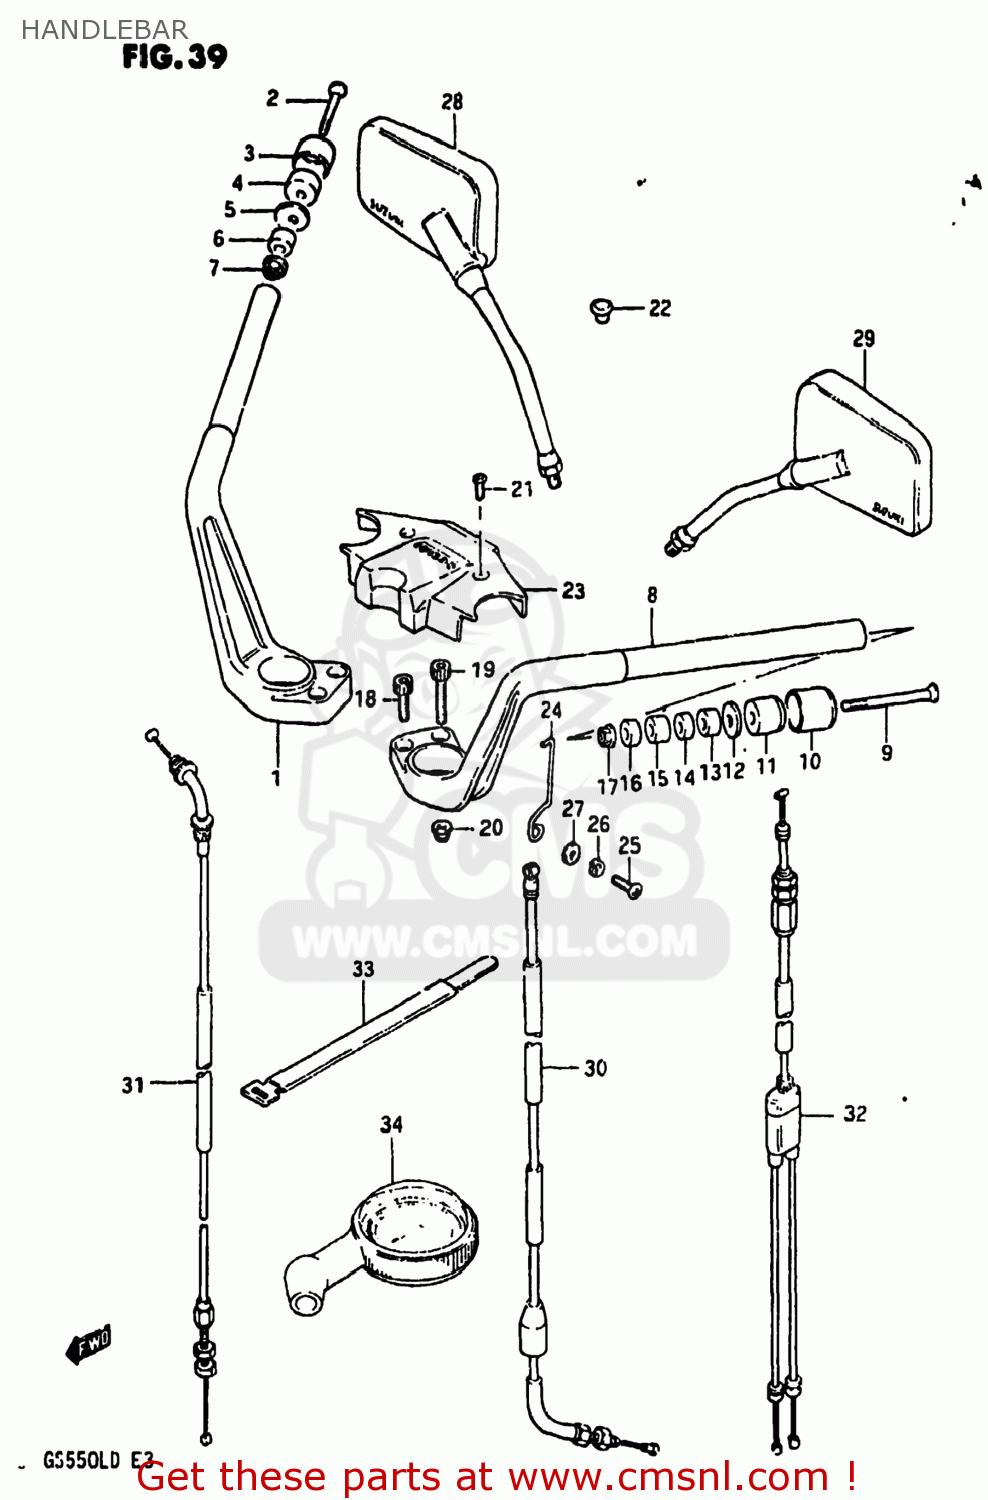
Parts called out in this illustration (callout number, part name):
1	HANDLEBAR,RIGHT
2	SCREW
3	CAP,BALANCER
4	BALANCER,HANDLE
5	SPACER,BALANCER
6	EXPANDER,HANDLE BALANCER
7	NUT
8	HANDLEBAR,LEFT
9	SCREW
10	CAP,BALANCER
11	BALANCER,HANDLE
12	SPACER,BALANCER
13	BALANCER,HANDLEBAR INNER
14	EXPANDER,HANDLE
15	BALANCER,HANDLEBAR INNER
16	EXPANDER,HANDLE
17	NUT
18	BOLT
19	BOLT
20	NUT
21	SCREW
22	CAP(OD:14)
23	PAD,HANDLE
24	GUIDE,CABLE
25	SCREW 6X12
26	LOCK WASHER
27	WASHER
28	MIRROR ASSEMBLY,REAR VIEW
29	MIRROR ASSEMBLY,REAR VIEW
30	CABLE ASSY,CLUTCH
31	CABLE ASSEMBLY,THROTTLE
32	CABLE COMP,STARTER
33	CLAMP(L:250)
34	GAUGE ASSY,AIR PRESSURE
